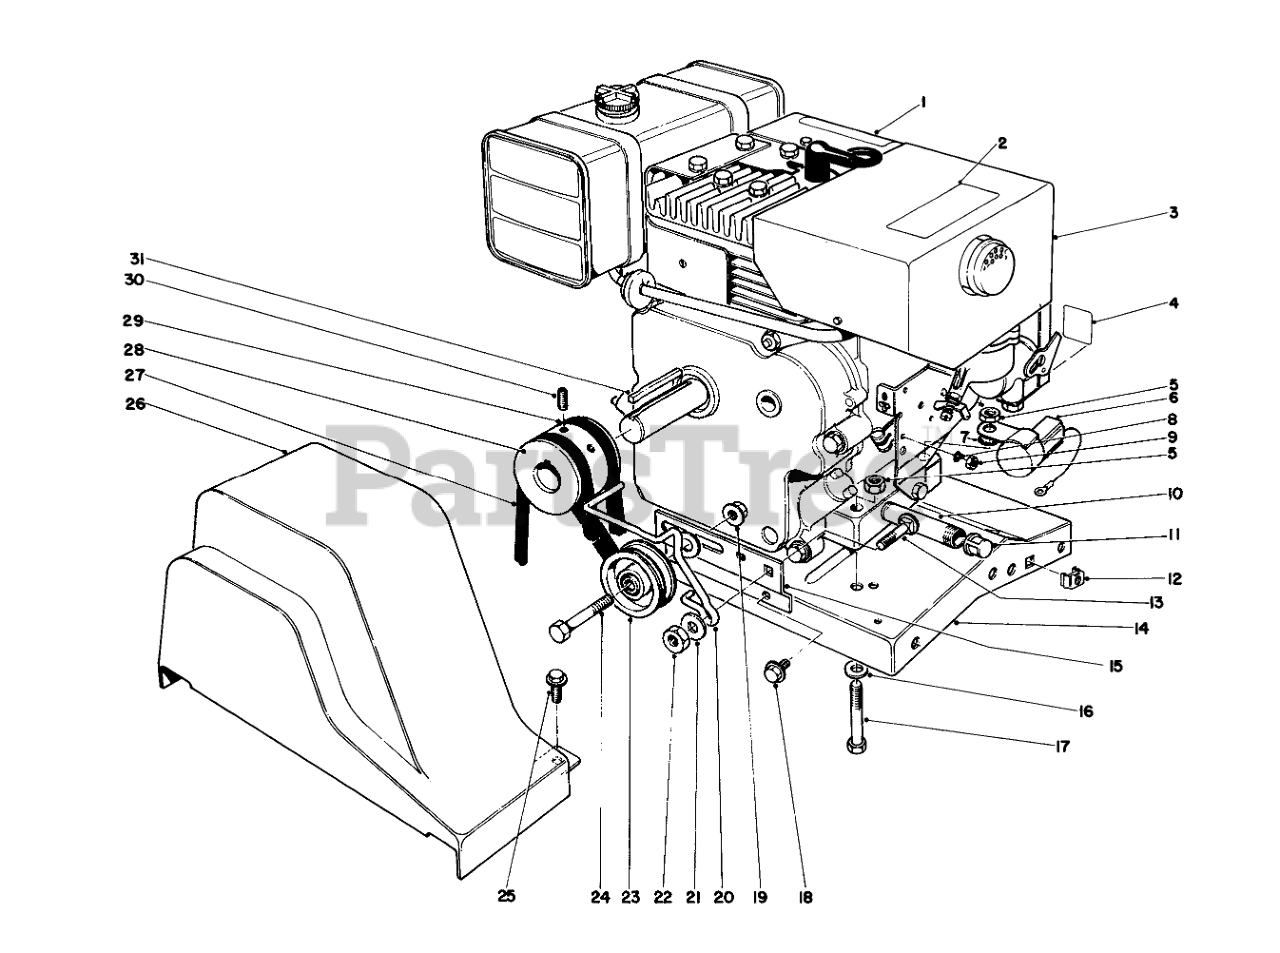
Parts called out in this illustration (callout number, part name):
1	Decal-Hazard
2	Decal Hot Surface Warning
3	Engine
4	CHOKE DECAL
5	NUT-LOCK, NI
6	INTERLOCK MODULE
7	WASHER-LOCK, INTERNAL
8	WASHER-LOCK/INT
9	NUT-LOCK
10	NIPPLE-PIPE
11	CAP-PIPE
12	Retained Nut
13	SCREW-CARR
14	Base-Engine
15	BELT IDLER BRKT
16	WASHER-PLAIN
17	SCREW-HH
18	SCREW-HHFTF
19	NUT-HHF, WHIZ
20	BELT GUIDE
21	WASHER-FLAT
22	NUT-HEX
23	PULLEY B
24	SCREW-HH
25	SCREW-HWH
26	BELT GUARD
27	V-BELT
28	ENGINE PULLEY
29	V-BELT
30	Screw-Set
